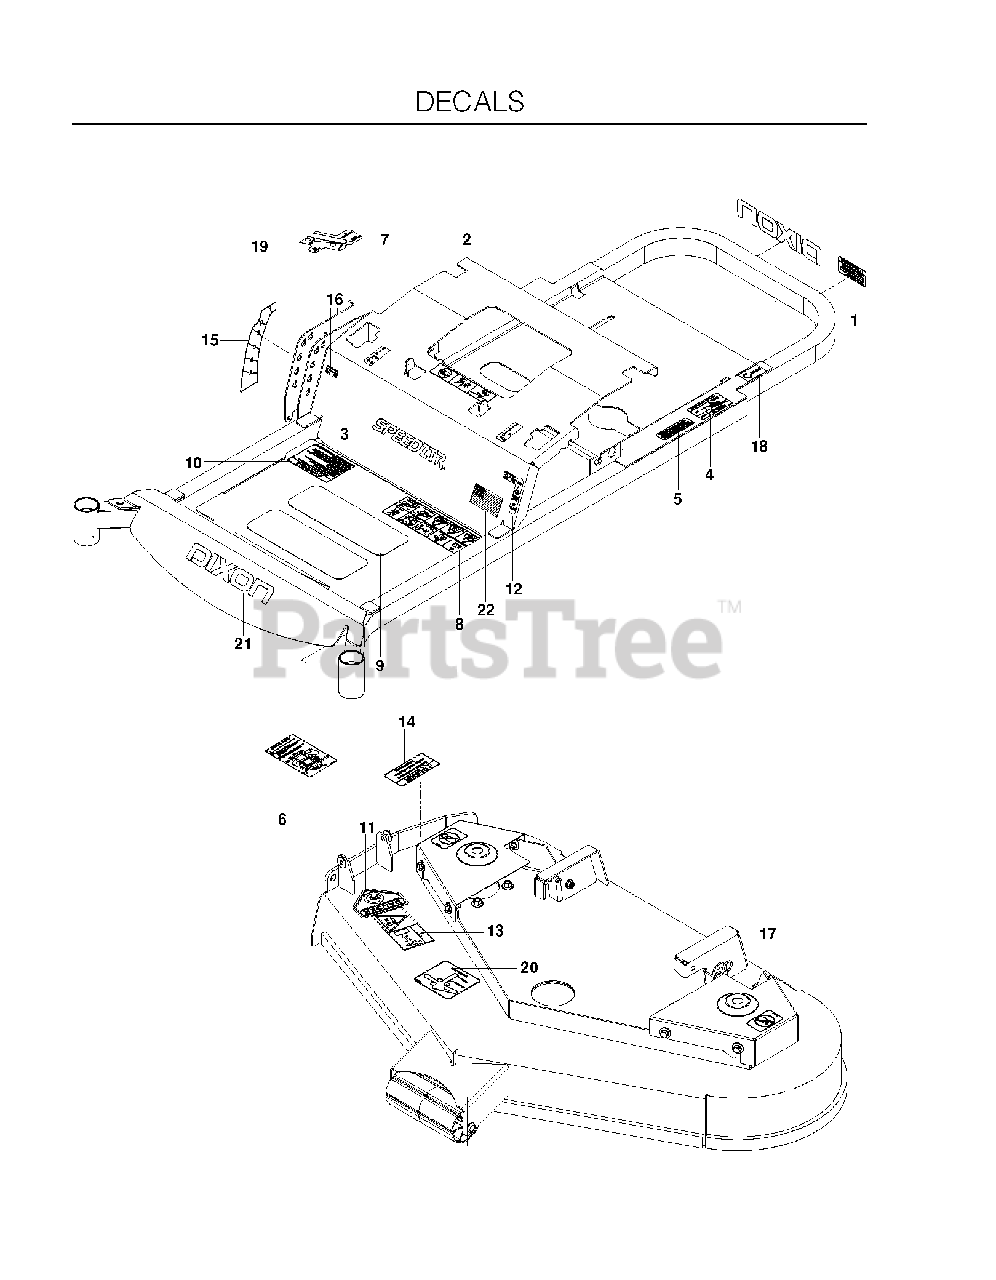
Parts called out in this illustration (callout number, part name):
1	DECAL, PROP. 65
3	DECAL, SPEEDZTR, 8"
4	DECAL, DO NOT MOUNT
5	DECAL, WARNING SPARK ARRESTOR
6	DECAL, SERVICE
7	DECAL, MOTION CONTROL
8	DECAL, SAFETY WARNING
9	ANTI-SKID PAD
10	DECAL, WARNING
11	DECAL, CPSC
12	DECAL, PARK BRAKE
13	DECAL, EURO SEVERING
14	DECAL, DANGER
15	DECAL, HEIGHT
16	DECAL, TRACKING
17	DECAL, NO STEP
18	DECAL, ECM, AUSTRALIA
19	DECAL, CONTROLS PANEL, DIX
20	DECAL, BELT ROUTING
22	DECAL, FLAG
